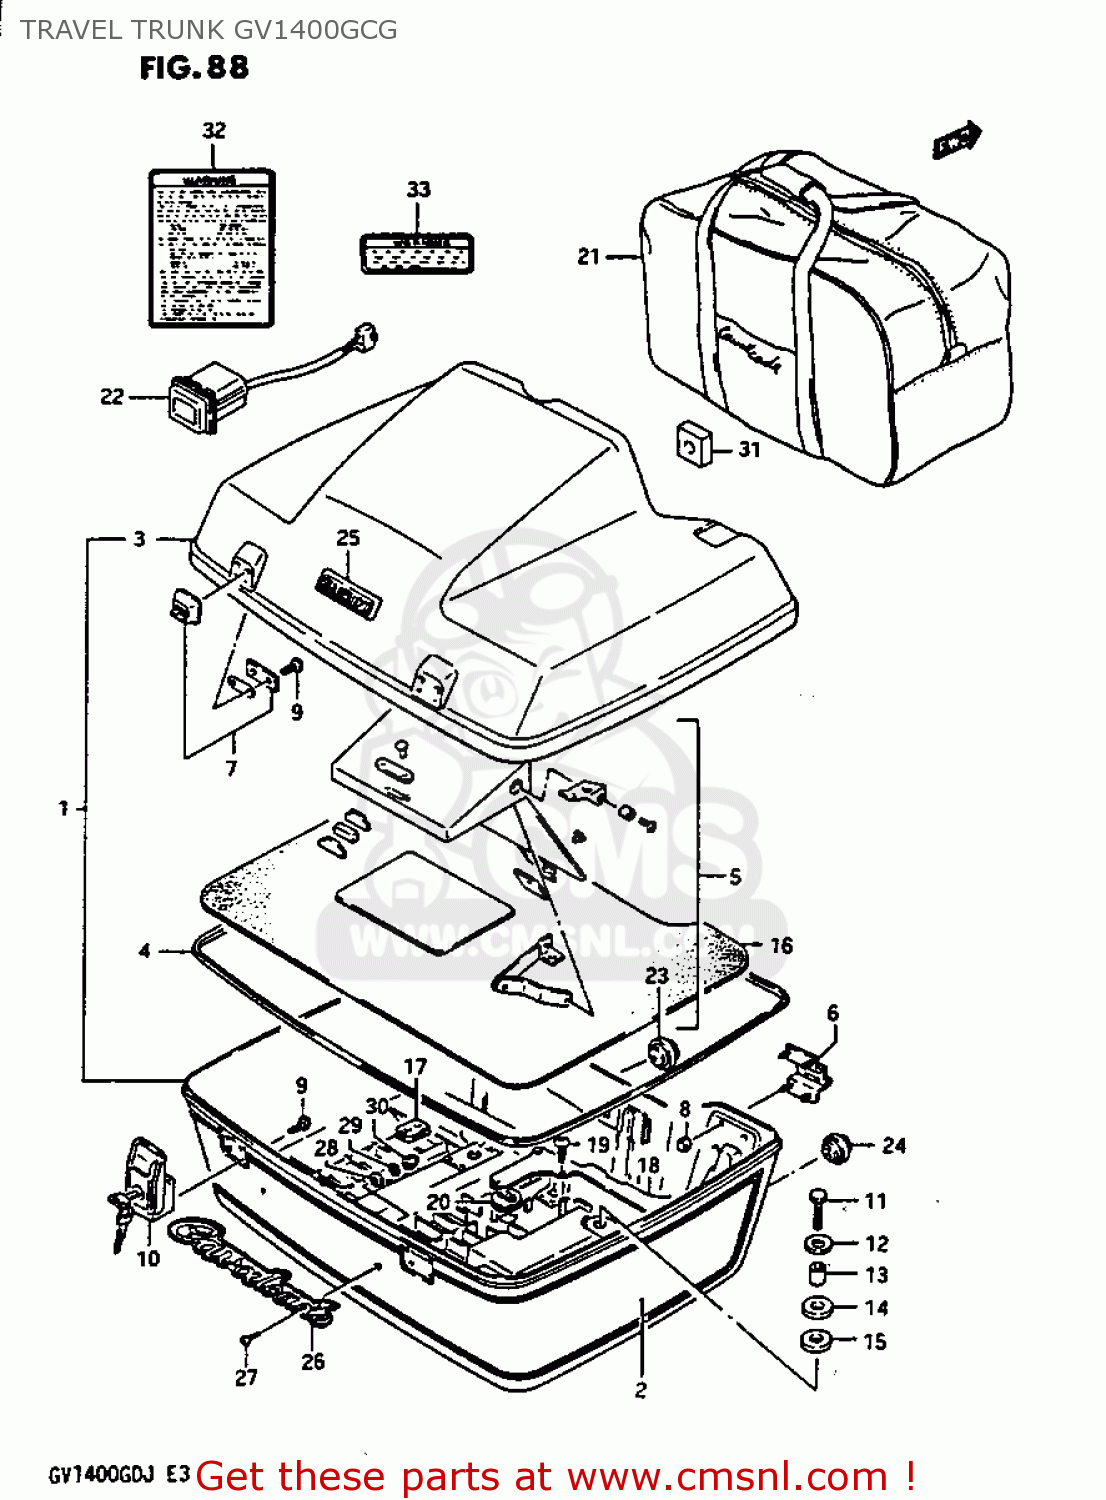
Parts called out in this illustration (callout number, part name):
1	TRUNK ASSY, TRAVEL
2	TAPE SET,TRAVEL TRUNK
3	LID,TRAVEL TRUNK
4	SEAL,TRAVEL TRUNK LID
5	MIRROR,TRAVEL TRUNK
6	HINGE,TRAVEL TRUNK
7	PLATE,TRUNK LID LOCK
8	NUT
9	SCREW
10	LOCK SET,SIDE BAG
11	BOLT
12	WASHER
13	SPACER(6.3X9.3X16.5)
14	CUSHION
15	CUSHION
16	SEAT,TRAVEL TRUNK BODY
17	GROMMET
18	COVER, AIR HOSE
19	SCREW
20	GROMMET
21	LUGGAGE BAG,TRAVEL TRUNK
22	SWITCH ASSEMBLY,AIR AUXILIARY
23	GROMMET
24	GROMMET, WIRE
25	EMBLEM,TRAVEL TRUNK,UPPER
26	EMBLEM,TRAVEL TRUNK,LOWER
27	SCREW
28	WASHER
29	WASHER
30	NUT
31	SEAL
32	LABEL (WARNING TRAVEL T
33	LABEL, WARNING
